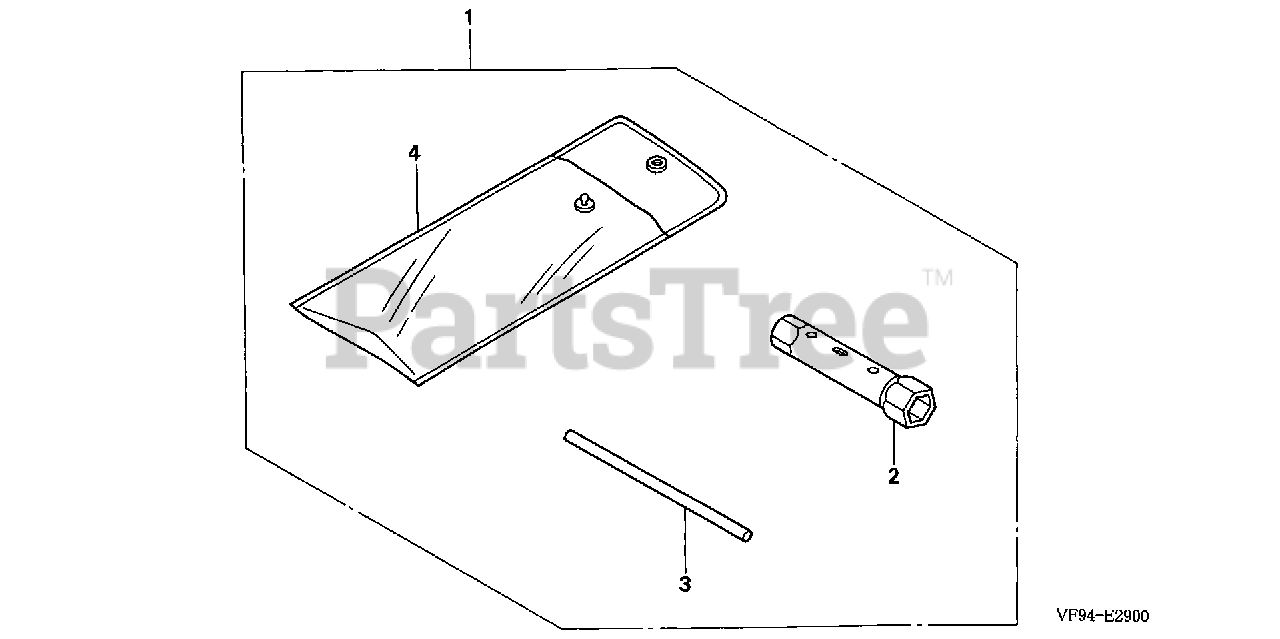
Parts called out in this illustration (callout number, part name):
2	WRENCH, SPARK PLUG
3	BAR A, HANDLE
4	BAG, TOOL (160MM)
